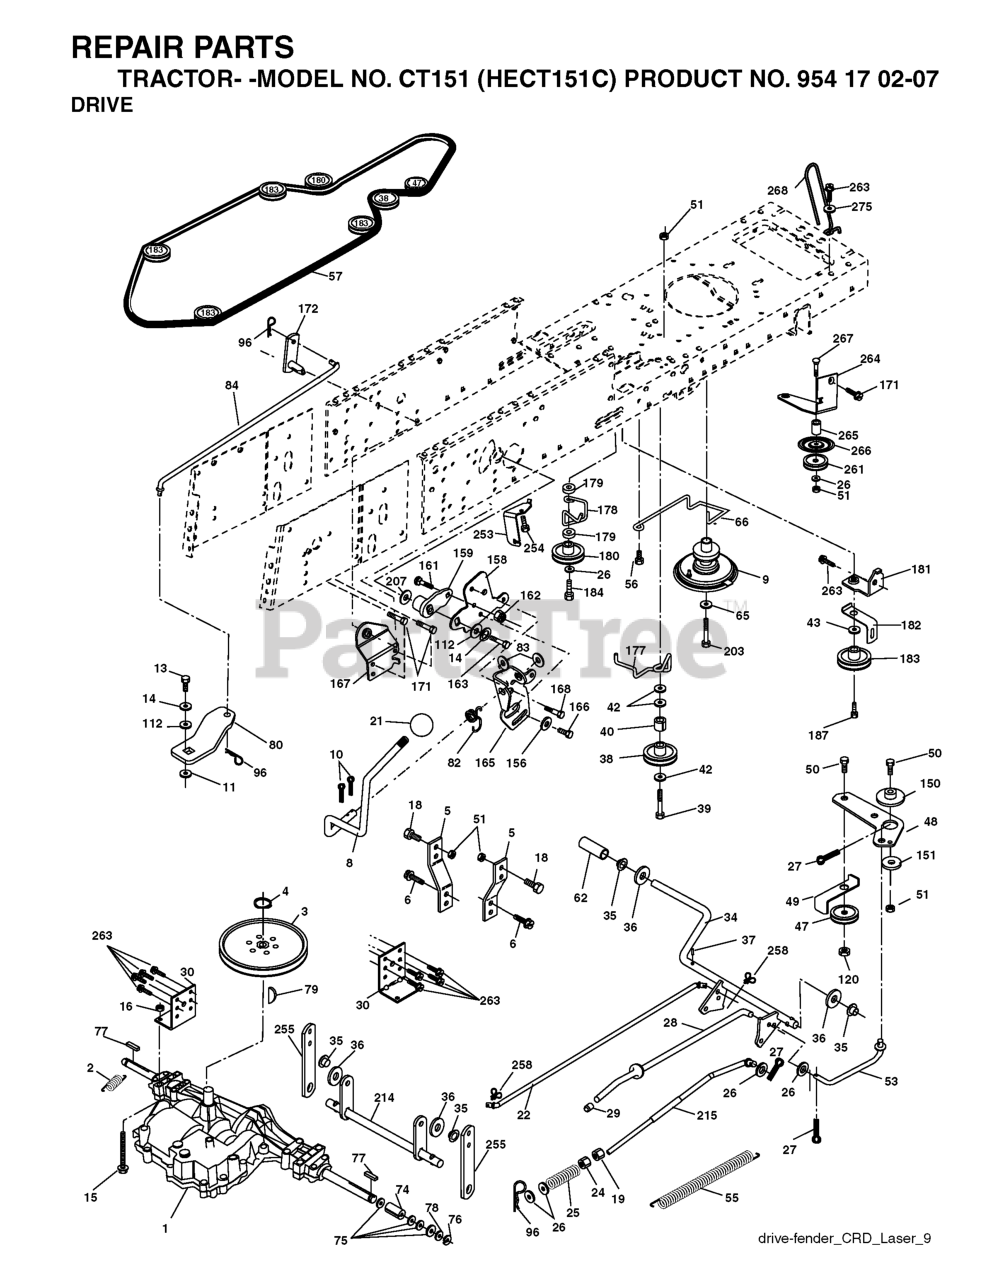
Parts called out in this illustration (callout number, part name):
2	SPRING,BRAKE RETURN
3	PULLEY
4	RETAINING RING LT
5	STRAP TORQUE
6	SCREW 5/16"
8	ROD.SHIFT.FENDER.ADJ.LT.CRD
9	RP CLUTCH.NORAM.2002
10	PIN COTTER
11	WASH-SHFT PLT LT
13	BOLT 1/4-28X3/4
14	LOCKWASHER
15	BOLT HEX 5/16-18 GR 5
16	NUT.71038.31-18.HEX.NYLOCK
19	NUT
21	KNOB.DUCKHEAD.1/2
22	ROD
24	NUT
25	SPRING ROD LT
26	WASHER
27	COTTER PIN
28	ROD, PARKING BRAKE
29	PLUNGER CAP
30	BRKT, MOUNT TRNSAXLE
34	SHAFT, FOOT PEDAL
35	BEARING.NYLON
37	DRIVE PIN
38	PULLEY.FLAT
42	WASHER
47	IDLER PULLEY
48	BELLCRANK, CLUTCH
49	RETAIN BELT
50	BOLT.3/8-16X1.50
53	LINK, CLUTCH LT
55	SPRING, RETURN LT
56	SCREW.3/8-16
57	V-BELT.KEV.111"
62	COVER, PEDAL (1 2)
65	LOCKWASHER
66	KEEPER BELT ENGINE
74	SPACER AXLE
77	SQUARE KEY
79	KEY STD (1373) DANA
82	SHIFT SPRING
83	WASHER
96	RETAINER M
120	NUT LOCK FLG 3/8-16 UNC
150	BUSHING.BELLCRANK.GRD.DR
151	WASHER 12/32X2X10GA
156	WASHER.SRRTD.5/16
158	BRACKET
159	RB HUB.SHIFT
161	BOLT
162	NUT.CROWNLOCK.1/4
165	RP BRACKET
166	CAPSCREW.HXHD.FLG.5/16-18X.625
167	BRACKET.SUPT.SHIFT.CRD
168	BOLT.SHOULDER.5/16-18X
172	SHAFT
180	PULLEY.FLAT.IDLER
181	BRACKET
182	BELT GUIDE
184	SCREW.HXWSH.3/8
187	BOLT.5/16-18X1.25
203	BOLT.HEX.7/16-20 X 5
207	WASHER NYL
214	LEVER
254	SCREW 3/8-16X1
255	SHAFT
258	CLIP RETAINER
261	FLAT IDLER PULLEY
263	SCREW, 3/8-16X3/4
265	SPACER IDLER
266	PROTECTOR
268	GUARD MUFFLER
275	WASHER
